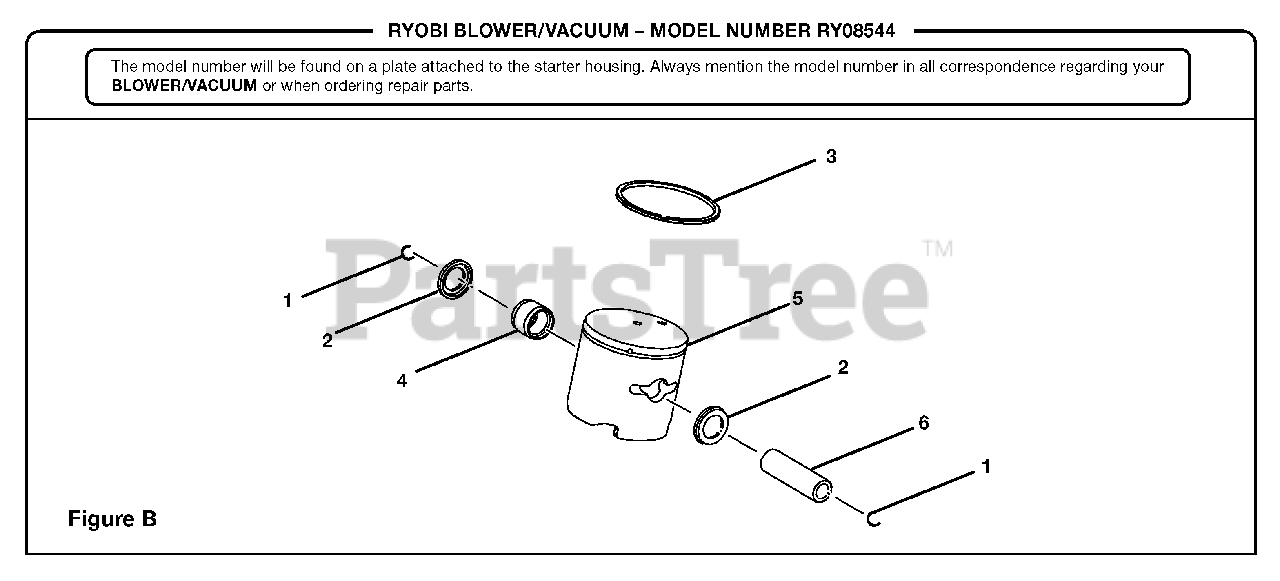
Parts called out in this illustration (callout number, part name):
1	Circlip Pin
2	Washer
3	Piston Ring
4	Needle Bearing
6	Piston Pin
